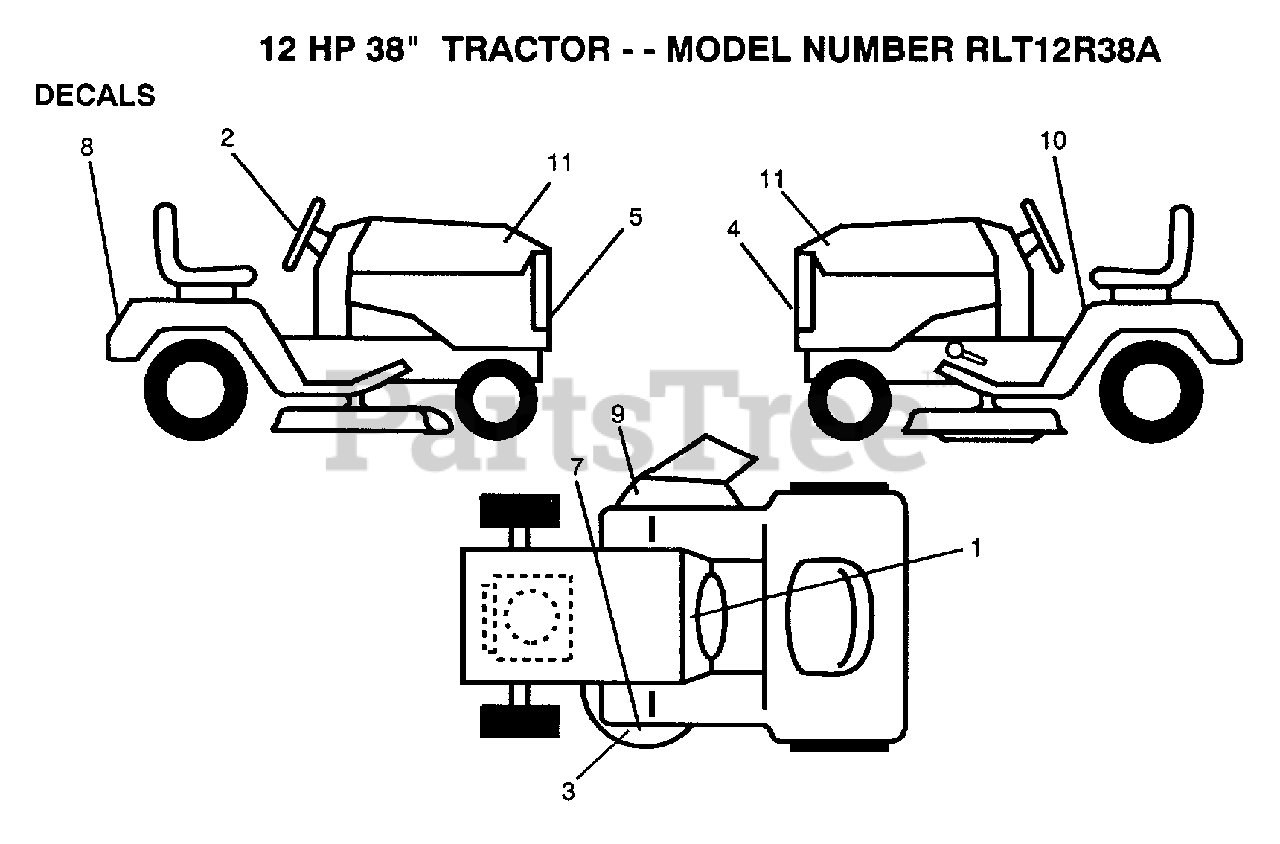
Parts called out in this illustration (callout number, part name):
2	"DECAL,STR WHL"
4	GRILL DECAL
5	IND HGT DECK DECA
7	DECAL YT
8	FENDER DECAL
9	DECAL WARNING
